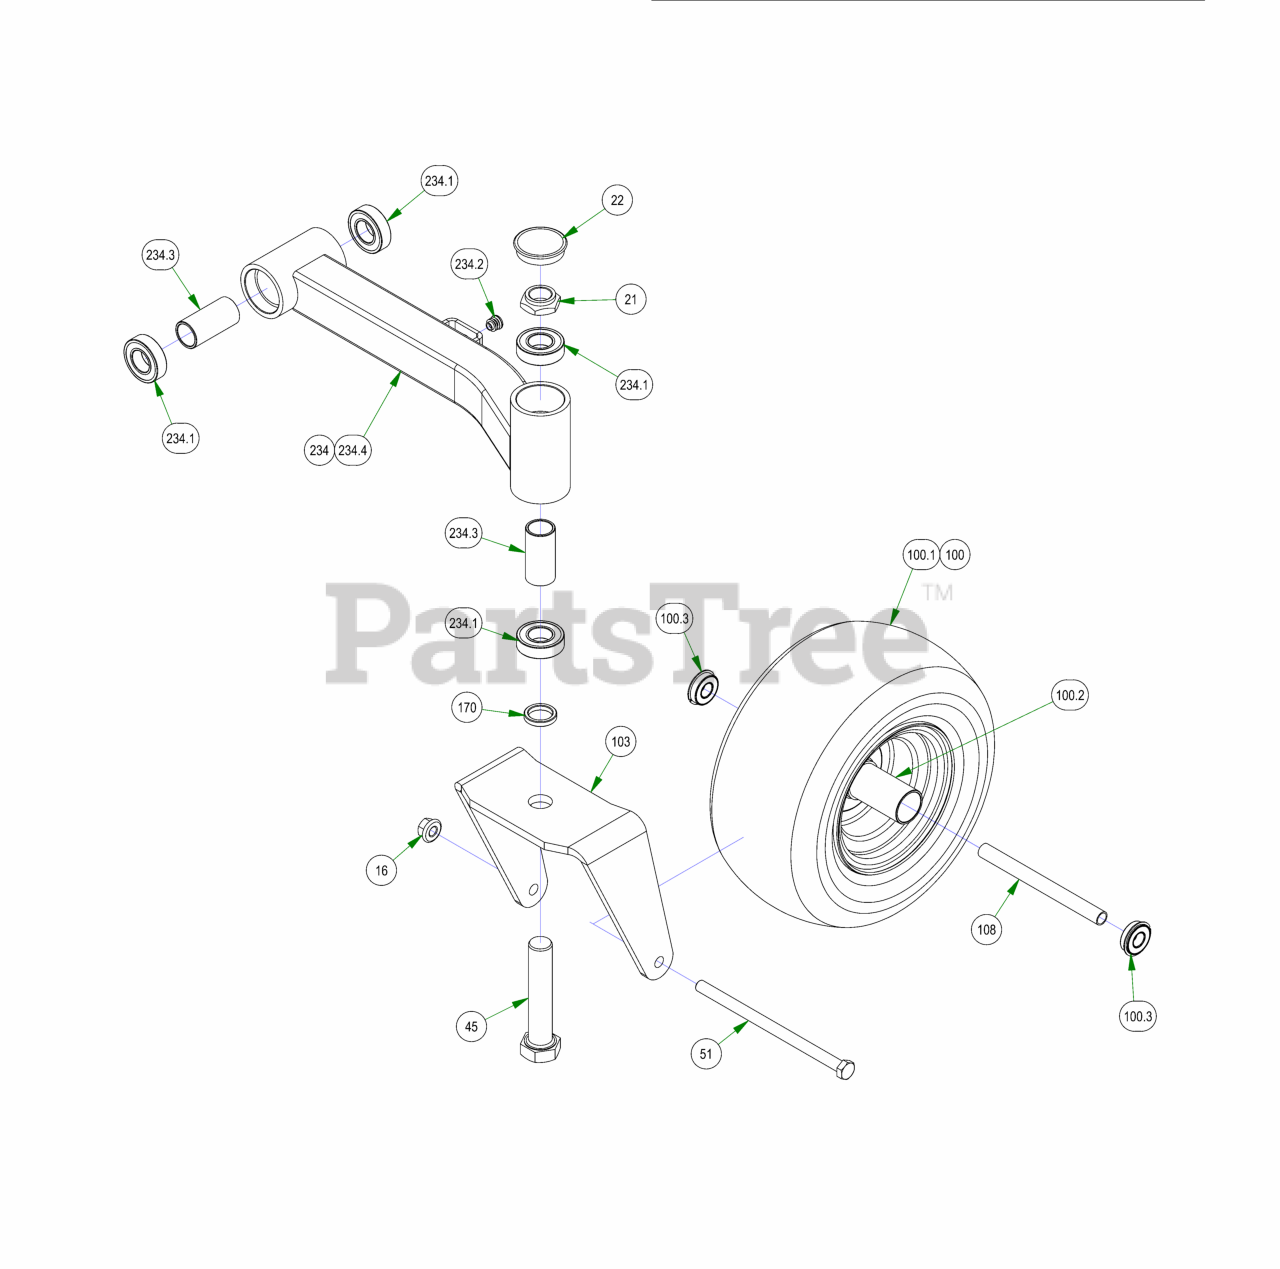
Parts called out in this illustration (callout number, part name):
16	1/2-13 NYLON INSERT FLANGE LOCKNUT ZINC
21	1"-14 NYLON INSERT JAM LOCKNUT ZINC
22	2017 Bearing Cover
45	1"-14 X 5 HEX CAP SCREW (GR.8) ZINC YELLOW
51	1/2-13 X 8-1/2 HEX CAP SCREW (GR.5) ZINC
100	13x6.5-6 Black Tire and Wheel Assembly
100.1	13 x 6.50 - 6 Tire
100.2	Front Tire Rim
100.3	Ball Bearing w/Retainer, 99502H-NR, .625 Bore x 1.375 OD x .4375 Width
103	2017 ZT Front Fork
108	Front Wheel Spanner
170	Spacer, 1x1.375x.25
234	2021 ZT Suspension Arm Assembly Left (48", 54", & 60")
234.1	1641 BEARING W/2 CONTACT RUBBER SEALS
234.2	5/8 Round Insert
234.3	2016 Front Bearing Spacer
234.4	2021 ZT LH Front Arm
